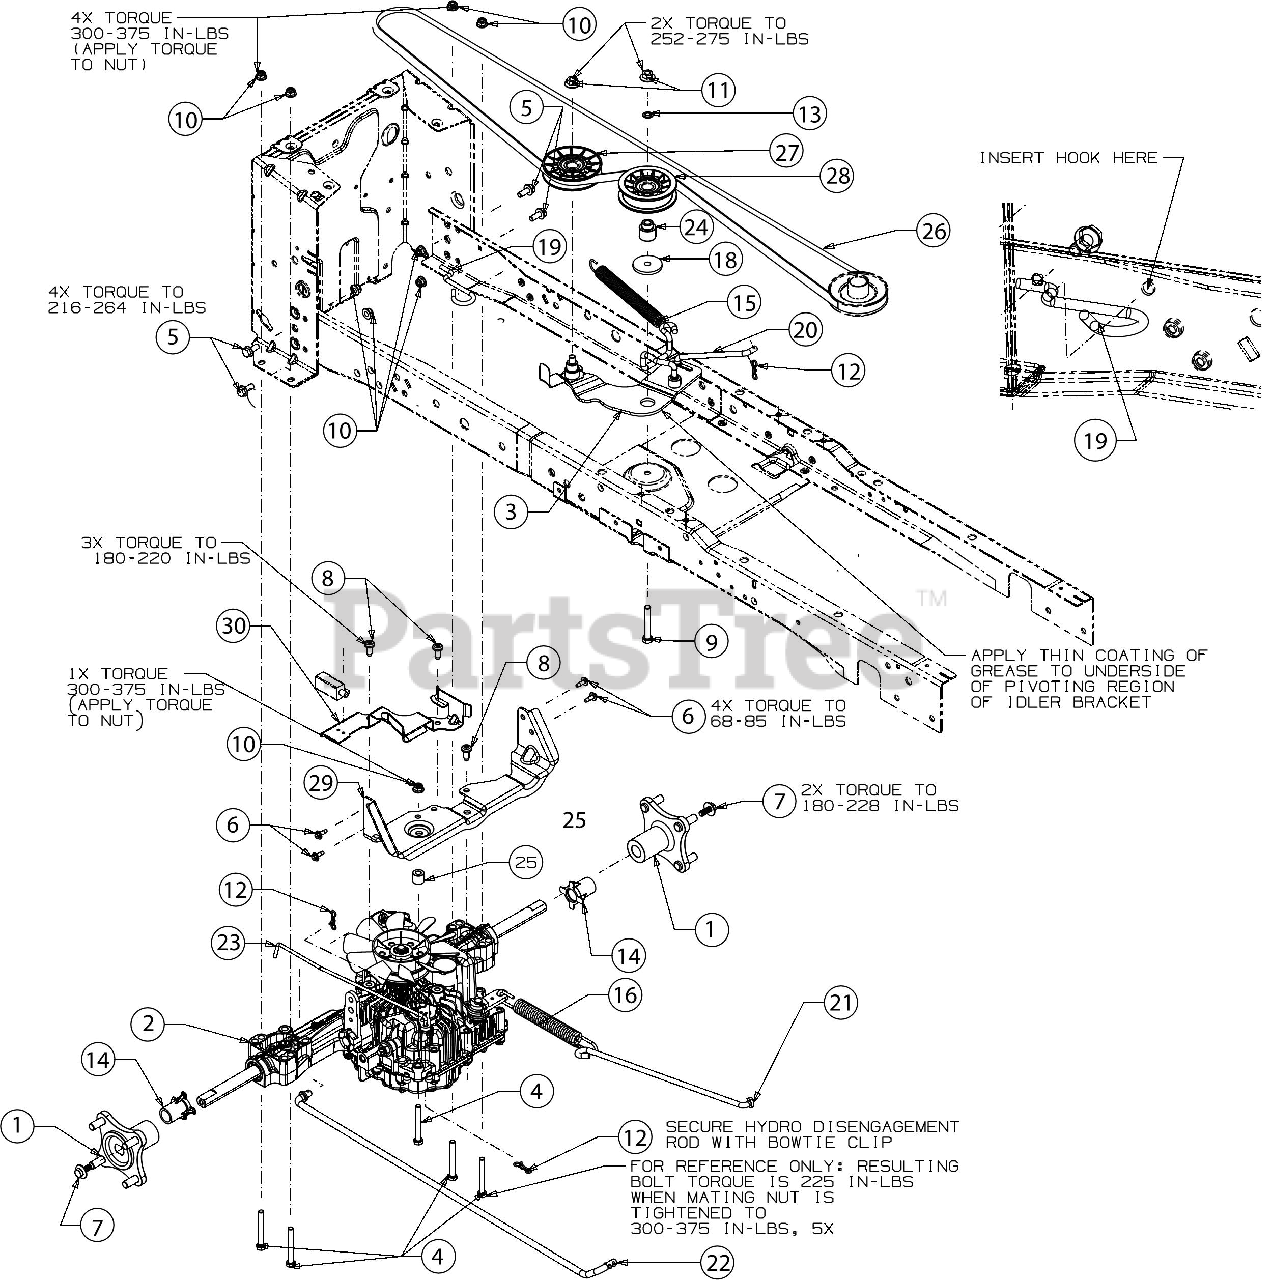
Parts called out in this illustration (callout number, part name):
1	HUB ASSEMBLY-WHEEL DD
2	TRANSMISSION ASSEMBLY
3	IDLER BRACKET ASSEMBLY
4	SCREW 5/16-18 x 2.5 GR 5
5	SCREW 5/16-18
6	SCREW M6-1 x .625
7	SCREW 5/16-24 x .85 GR5
8	SCREW 5/16-18 x .750
9	SCREW 3/8-16 x 2.25 GR5
10	FLANGE LOCK NUT 5/16-18
11	FLANGE LOCK NUT
12	BOW TIE COTTER PIN 1/4-5/16
14	AXLE SLEEVE .765 ID x 1.575 LG
15	EXTENSION SPRING .790 DIA x 8.41
16	EXTENSION SPRING 0.90 DIA x 8.14
18	SHOULDER SPACER
19	DECK SPRING HOOK
20	IDLER BRACKET LINK ROD
21	BRAKE ROD
22	HYDRO CONTROL ROD
23	HYDRO DISENGAGEMENT ROD
24	SHOULDER SPACER
25	SPACER .34 x .75 x .63 LG
26	V-BELT A SEC x 91.10
27	V-IDLER PULLEY 3.56 OD
28	FLAT IDLER PULLEY 3.00 OD
29	TRANSMISSON MOUNTING BRACKET
